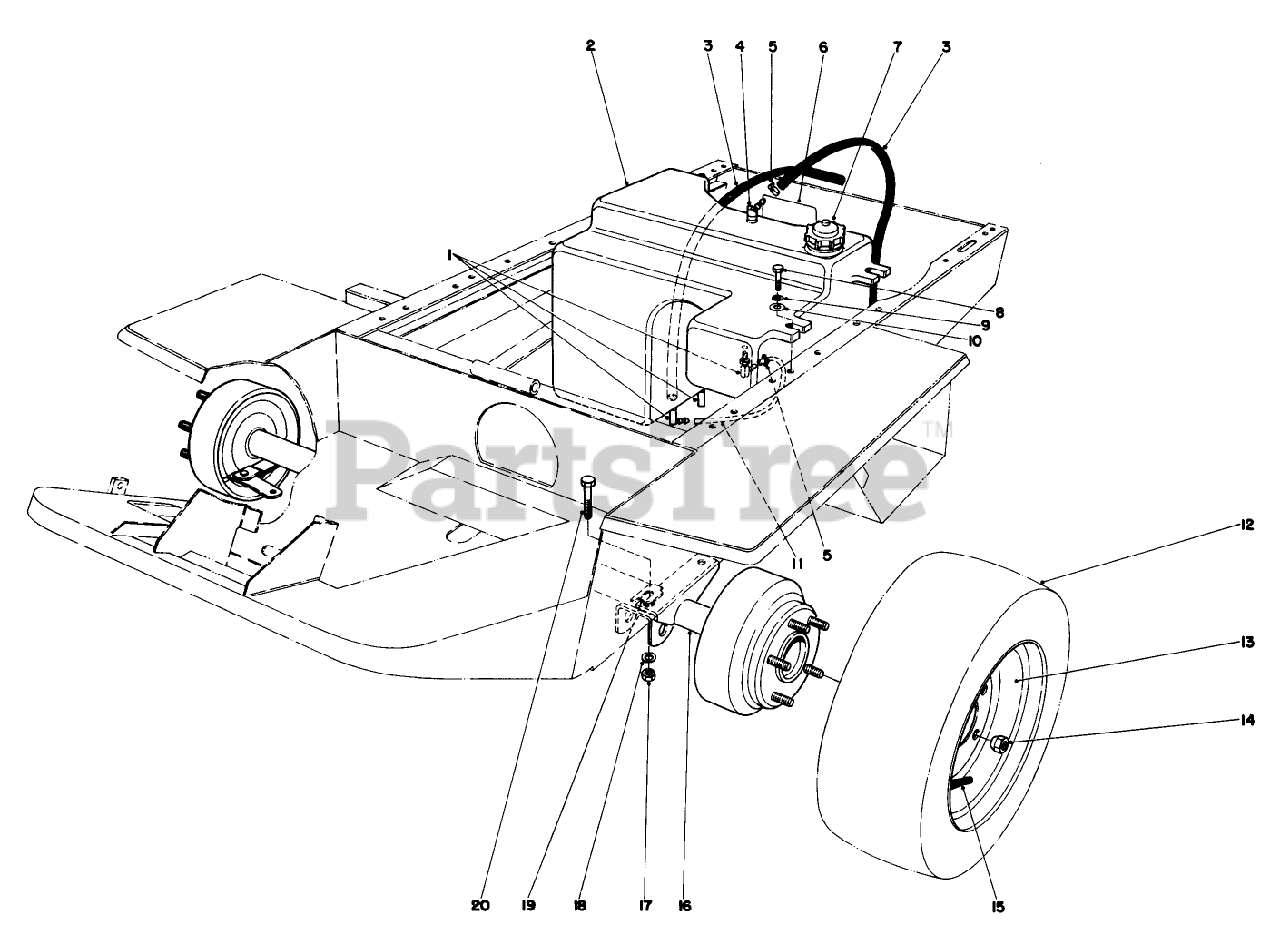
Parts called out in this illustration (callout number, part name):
2	GAS TANK
5	CLAMP-HOSE
6	DECAL-DANGER
7	GAS CAP ASM
8	SCREW-HH
9	WASHER-LOCK
10	WASHER
12	TIRE(20X8-10) 4-PLY
13	WHEEL ASM
14	NUT-WHEEL
17	NUT-HEX
18	SCREW-HH
19	SHIM-AXLE
20	SCREW-HH
